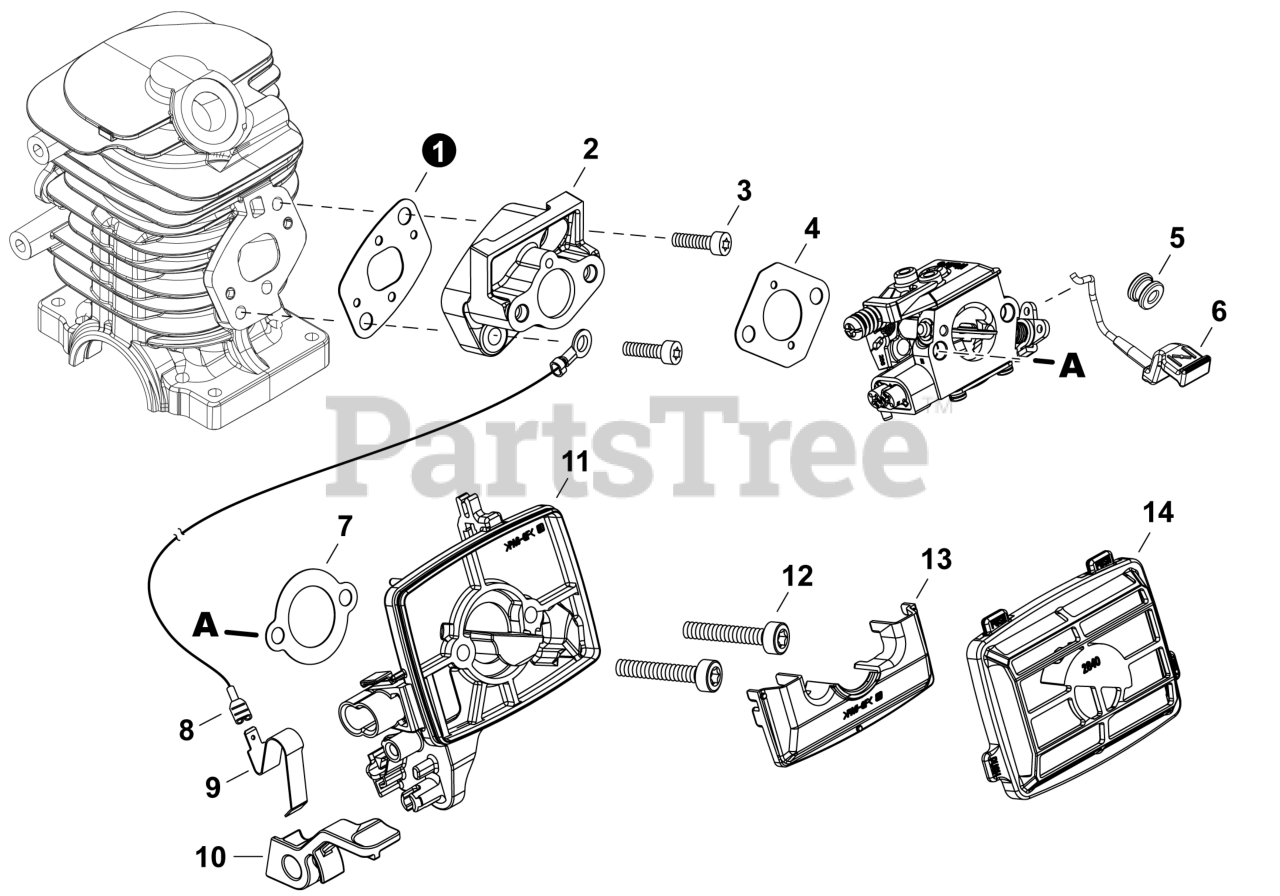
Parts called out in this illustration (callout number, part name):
1	GASKET, INTAKE
2	INSULATOR, INTAKE
3	BOLT, TORX 5x20
4	GASKET, INTAKE
5	GROMMET, CHOKE
6	KNOB, CHOKE
7	GASKET, INTAKE
8	LEAD 160MM
9	PLATE, CONTACT
10	SWITCH, STOP
11	BRACKET, AIR FILTER
12	BOLT, TORX 5x50
13	DUCT, AIR
14	FILTER, AIR
